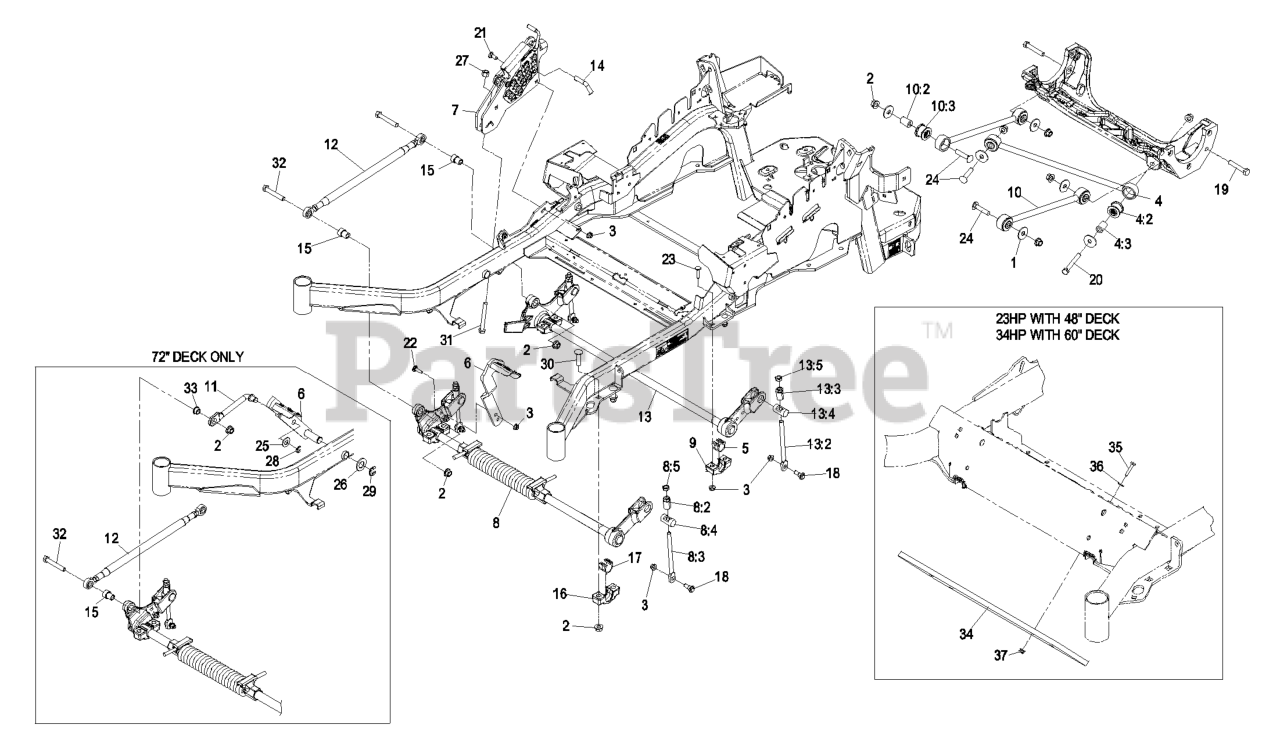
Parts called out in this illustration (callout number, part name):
1	WASHER-THRUST
2	Nut-Lock 1/2-13
3	NUT-HF, NI
4	PANHARD ROD ASM
4:2	BUSHING-SUSPENSION, RUBBER
5	BEARING-CROSS SHAFT, REAR
6	LEVER-FOOT
7	HOC ASM
8	FRONT DECK LIFT ASM
8:2	ADJUSTER-LIFT, DECK
8:3	LINK-ADJUSTER, DECK LIFT
8:4	TRUNNION
8:5	NUT-JAM
10	DECK STRUT ASM
10:2	BUSHING-SUSPENSION, RUBBER
11	LINK-LEVER, FOOT
12	SIDE LINK ASM
13:2	LINK-ADJUSTER, DECK LIFT
13:3	ADJUSTER-LIFT, DECK
13:4	TRUNNION
13:5	NUT-JAM
14	PIN-HOC
15	BUSHING-FLANGE
16	SUPPORT-CROSS SHAFT, BEARING
17	BEARING-CROSS SHAFT, FRON
18	SCREW-SHOULDER, HHF
19	SCREW-HH
20	SCREW-HH
21	BOLT-CARR
22	Bolt-Carriage 3/8-16 X 1 1/4
23	SCREW-CARR
24	SCREW-CARR
25	WASHER-FLAT
26	WASHER-FLAT
27	NUT-LOCK, NI
28	E-RING
29	RING-RETAINING, EXT
30	SCREW-CARR, SHORT NECK
31	BOLT-TAP
32	SCREW-HH
33	BUSHING-FLANGE
34	WEIGHT,TOE BOARD
35	SCREW-HH
36	WASHER-FLAT
